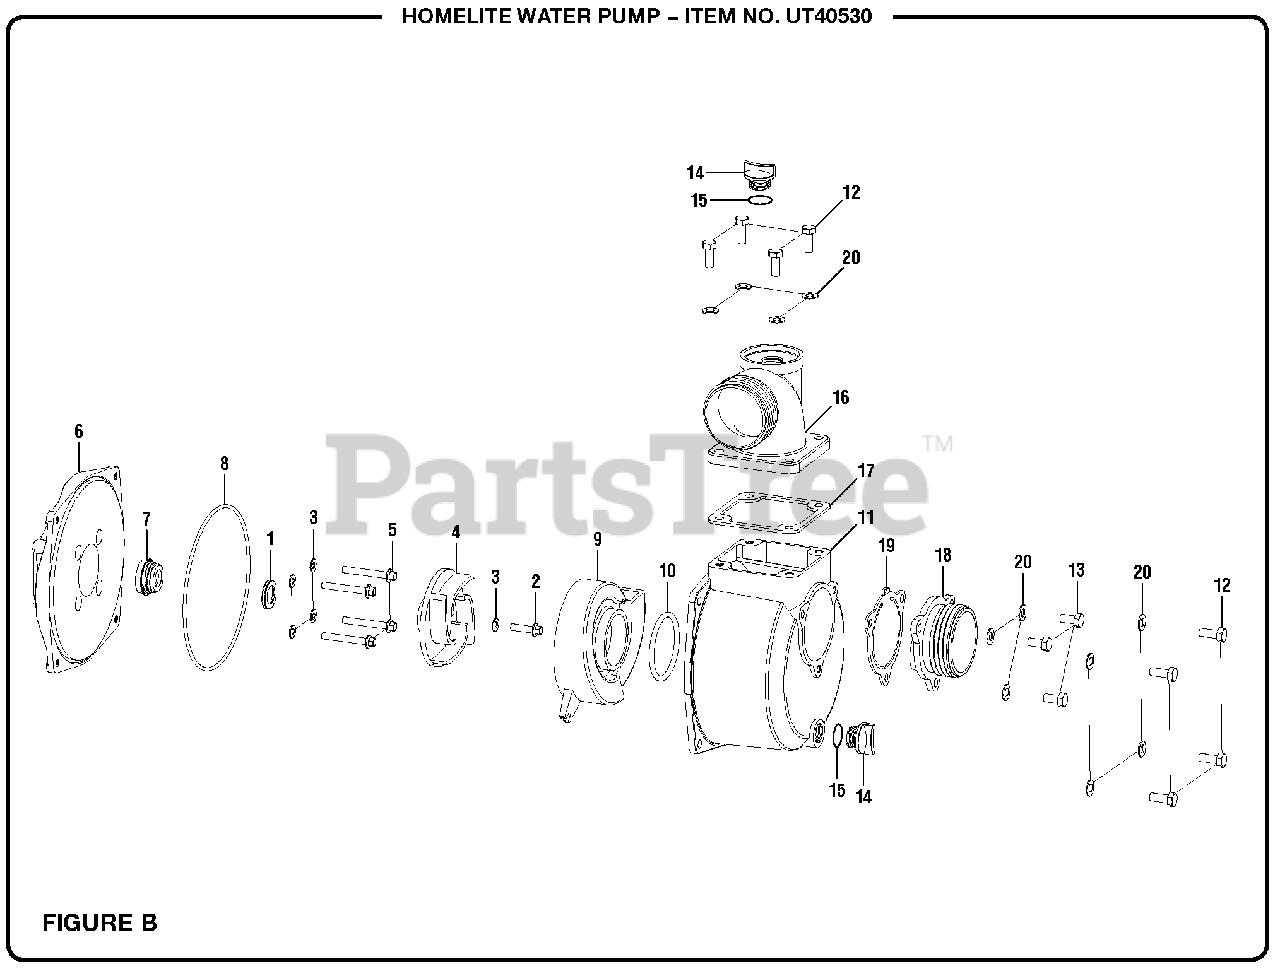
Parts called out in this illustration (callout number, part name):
1	Ceramic Seal Assembly
2	Bolt (5/16-24 x 30 mm)
3	Seal Washer
5	Bolt (5/16-24 x 60 mm, Flange Hd.)
6	Housing Cover
7	Mechanical Seal Assembly
8	O-Ring (Housing Cover)
9	Pump Volute
10	O-Ring (Volute)
11	Pump Housing
12	Bolt (M10 x 25 mm)
13	Bolt (M10 x 20 mm)
14	Pump Plug
15	O-Ring (Plug)
16	Pump Outlet
17	Gasket (Outlet)
18	Pump Inlet
19	Check Valve
20	Washer (M10)
